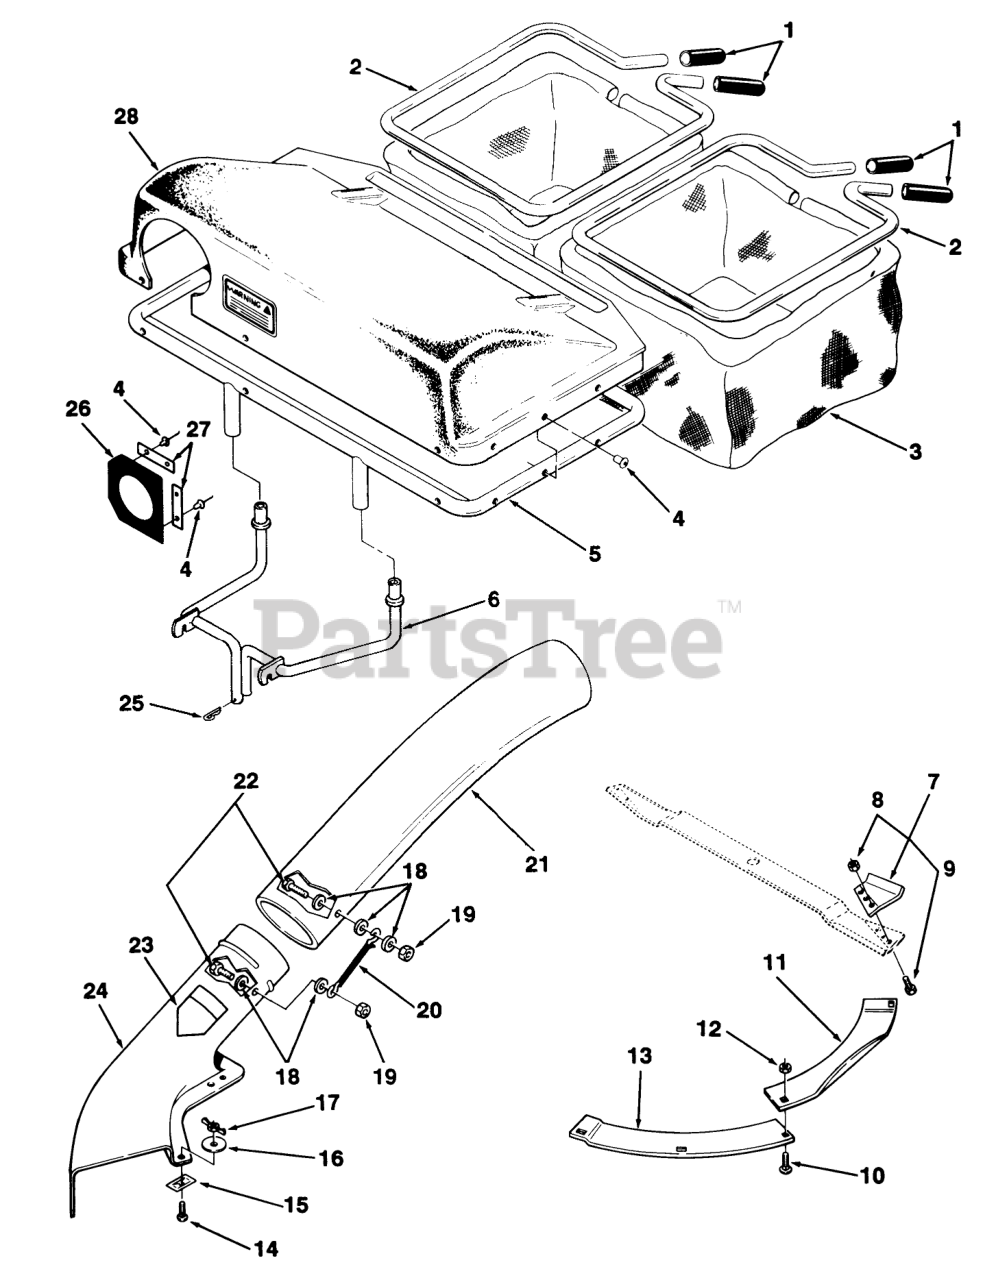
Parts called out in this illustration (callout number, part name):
1	GRIP
2	FRAME BAG B
3	BAG-BLACK(37"TWIN)
4	RIVET-BLIND
5	Frame
6	ASY-QUICK ATTACH B
7	Lift Tab Kit (Incl. Ref. #8 & 9)
8	NUT-LOCK 5/16-18
9	BOLT 5/16-18X5/8
10	Bolt
11	PLATE MOWER B
12	Nut
13	PLATE MOWER RING B (NS)
14	Bolt-Carriage
15	SPEED NUT 1/4-20
16	WASHER
17	WING NUT
19	Nut
20	Strap
21	Tube (Incl. Ref. # 18, 19 & 22)
22	Bolt
23	DECAL-DANGER
24	Elbow (Incl. Ref. #18, 19 & 22)
25	Hairpin
26	SEAL-CHUTE
27	STRAP-SEAL
28	TOP-BAG'R (37")
